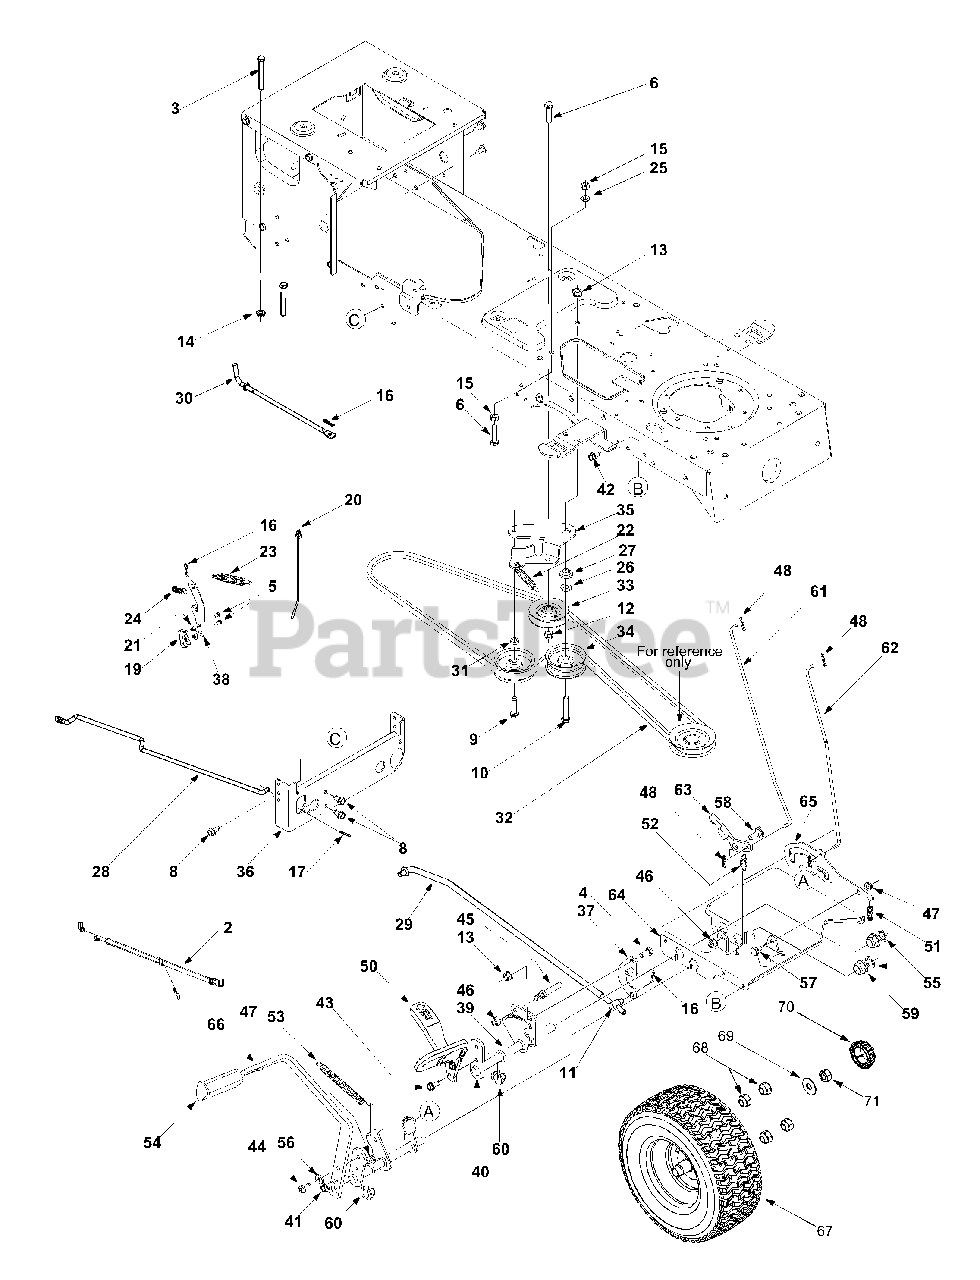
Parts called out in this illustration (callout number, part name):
2	Harness Assembly
3	Hex Bolt 5/16-18 x 2.75
4	Hex Bolt 3/8-16 x 0.75
6	Hex Bolt 3/8-16 x 1.5
7	TT Screw 1/4-20 x 0.5
8	AB Screw 5/16-12 x 0.75
9	TT Sems Screw 3/8-16 x 1.5
10	Hex Bolt 3/8-16 x 2.25
11	Ferrule
12	Hex Lock Nut 3/8-16
13	Flange Lock Nut 3/8-16
14	Flange Lock Nut
15	Hex Nut 3/8-16
16	Hairpin Clip
17	Hairpin Clip
18	Cable Tie
19	Switch: Spring
20	Cable Tie
21	Plate: Insulator Nut
22	Extension Spring
23	Extension Spring
24	Extension Spring
25	Lock Washer
26	Flat Washer
27	Shoulder Spacer
29	Control Rod
30	Disengagement Rod: Hydro
31	Spacer
32	V Belt
33	Idler Pulley
34	Flat Idler Pulley
42	AB Screw 5/16-12 0.75
43	LD Screw 5/16-18 x 0.75
44	TT Screw 5/16-18 x 0.75
45	Pin
46	Hex Lock Nut 3/8-16
47	Flange Lock Nut 5/16-18
48	Hairpin Clip
49	Hairpin Clip
50	Control Pedal: Hydro
51	Compression Spring
52	Extension Spring
53	Extension Spring
54	Brake Pedal
55	Flat Washer
56	Flat Washer
57	Shoulder Screw
58	Shoulder Screw
59	Hex Flange Bearing
60	Hex Flange Bearing
61	Control Rod: Brake Lock
62	Control Rod: Cruise
63	Cruise Latch
65	Lockout Bracket
68	Lug Nut 7/16-14
69	Flat Washer
70	Hubcap
71	Jam Nut 3/4-16
